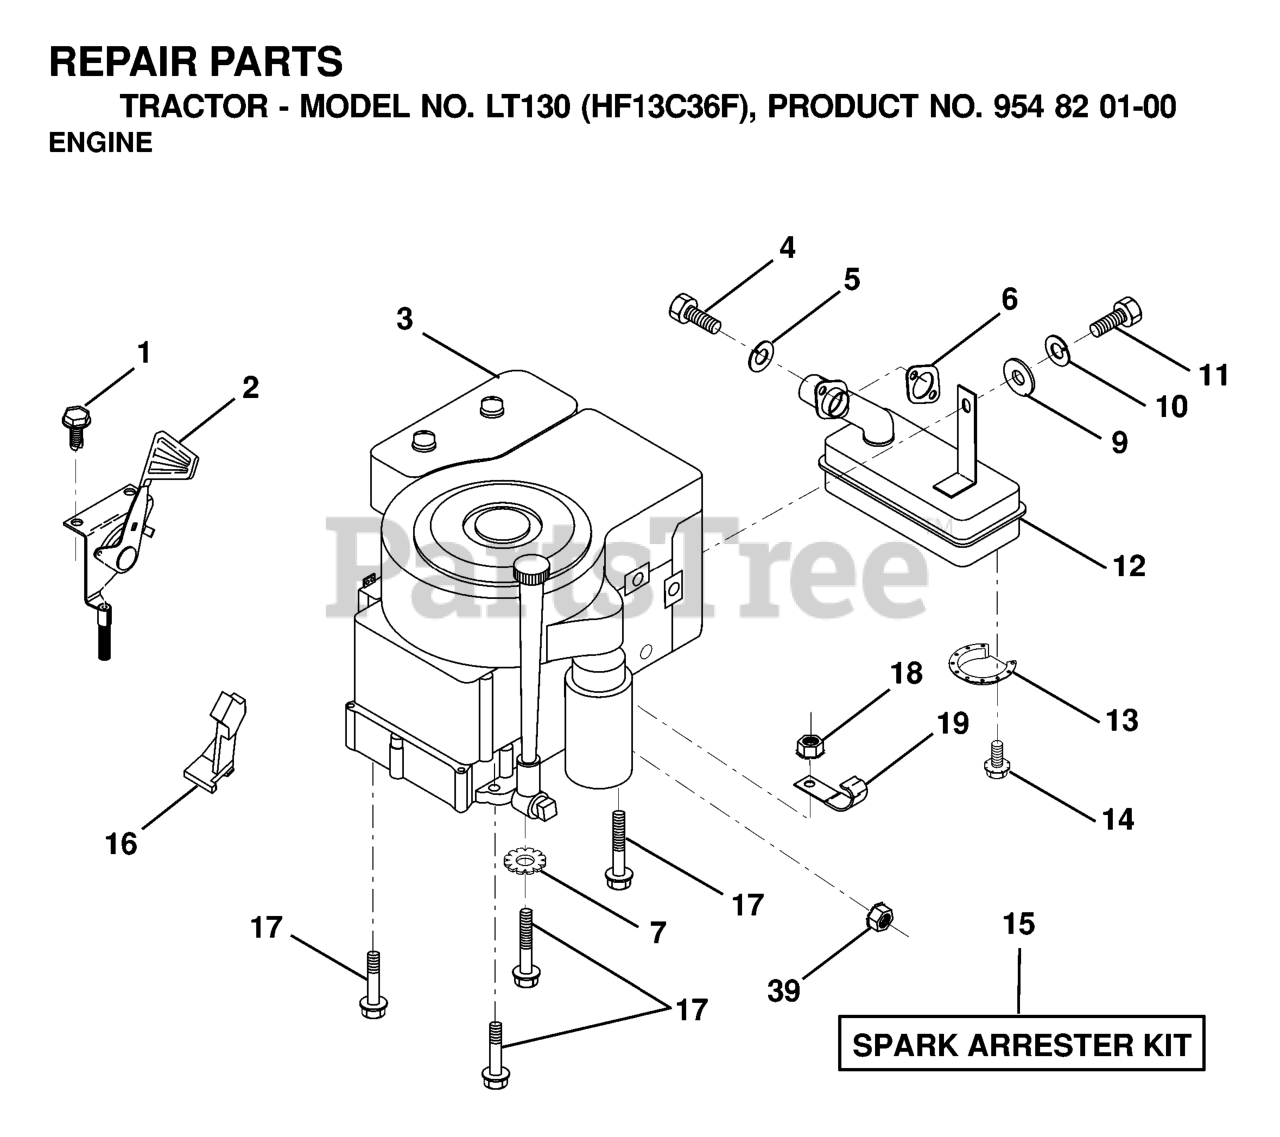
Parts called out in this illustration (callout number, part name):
1	SCREW LT
2	CONTROL.TH/CH.RH.BLK.FLG.EEC
4	SCREW
5	WASHER.LOCK.HVY.HLCL.SPR.5/16
6	REPL BY 532 27 22-93
7	LOCKWASHER
9	WASHER
10	LOCKWASHER
12	MUFFLER.SINGLE.B&S.12HP
13	DEFL MUFFLER LTV
14	SCREW
15	KIT.SPARK ARRESTOR 794945 B&S
16	STOP THROTTLE
17	SCREW LT
19	CLIP T
39	NUT FLANGE 1/4-20 STARTER NUT
